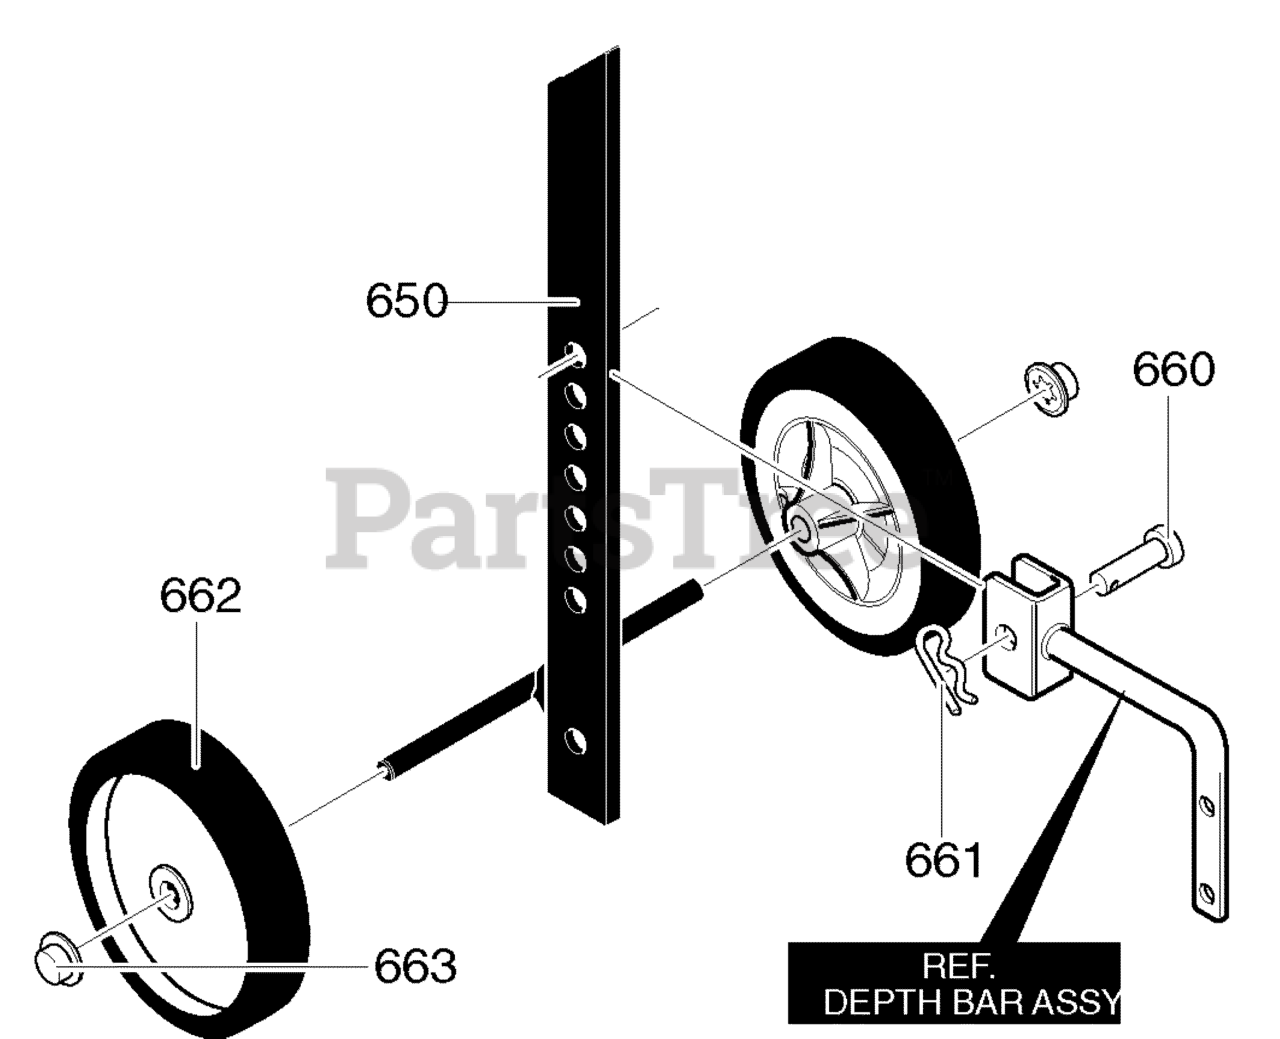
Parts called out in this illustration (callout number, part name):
650	Wheel Support Assy.
660	Clevis Pin
661	Hair Pin
662	Tire & Rim
663	Push On Nut
